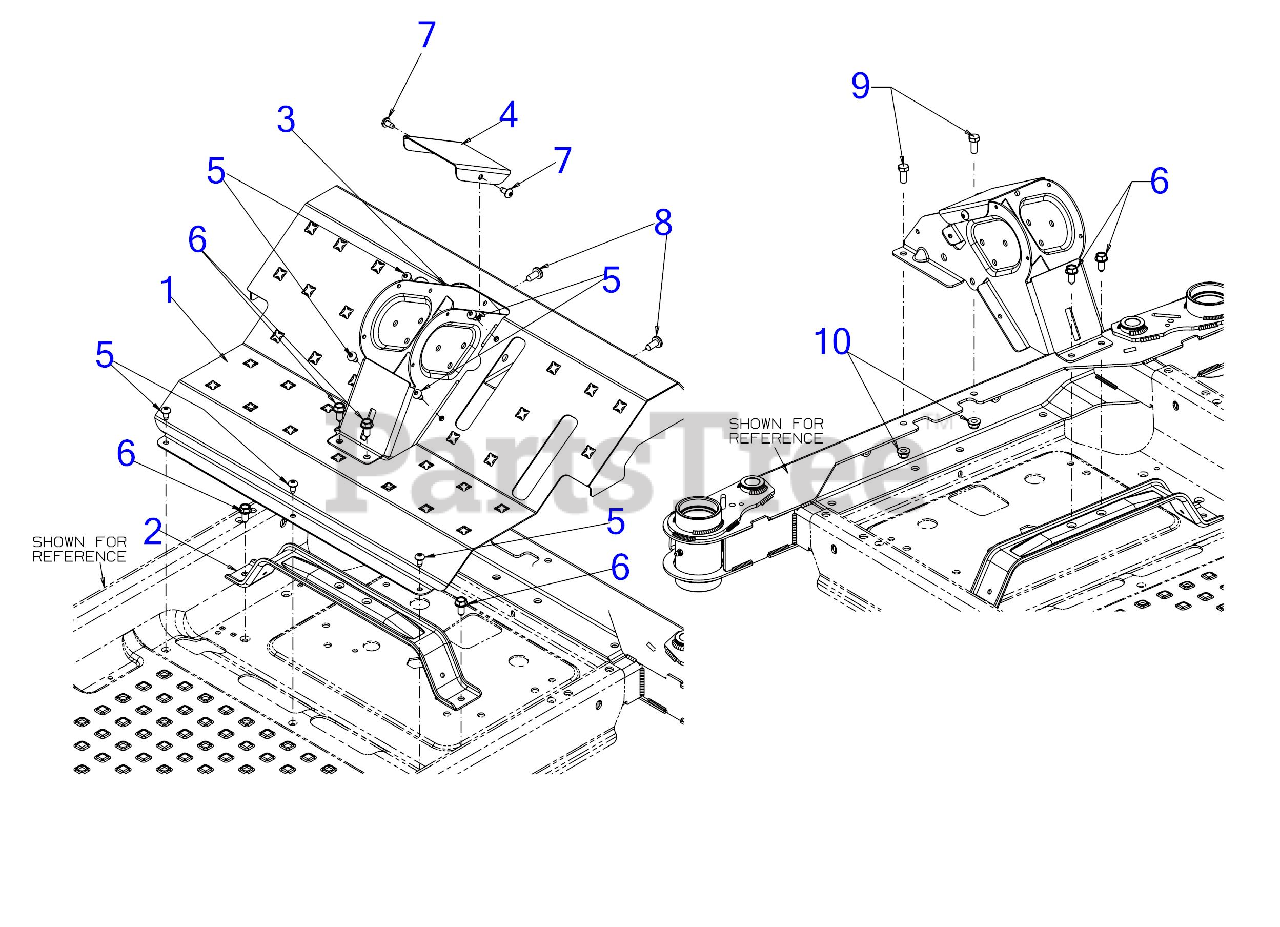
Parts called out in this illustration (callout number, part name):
5	SCREW 1/4-20 x .500
6	SCREW 5/16-18 x .750
7	SCREW 1/4-20 x .5
8	SCREW 5/16-18 x .750
9	SCREW 5/16-18 x .75 GR5
10	FLANGE LOCK NUT 5/16-18
